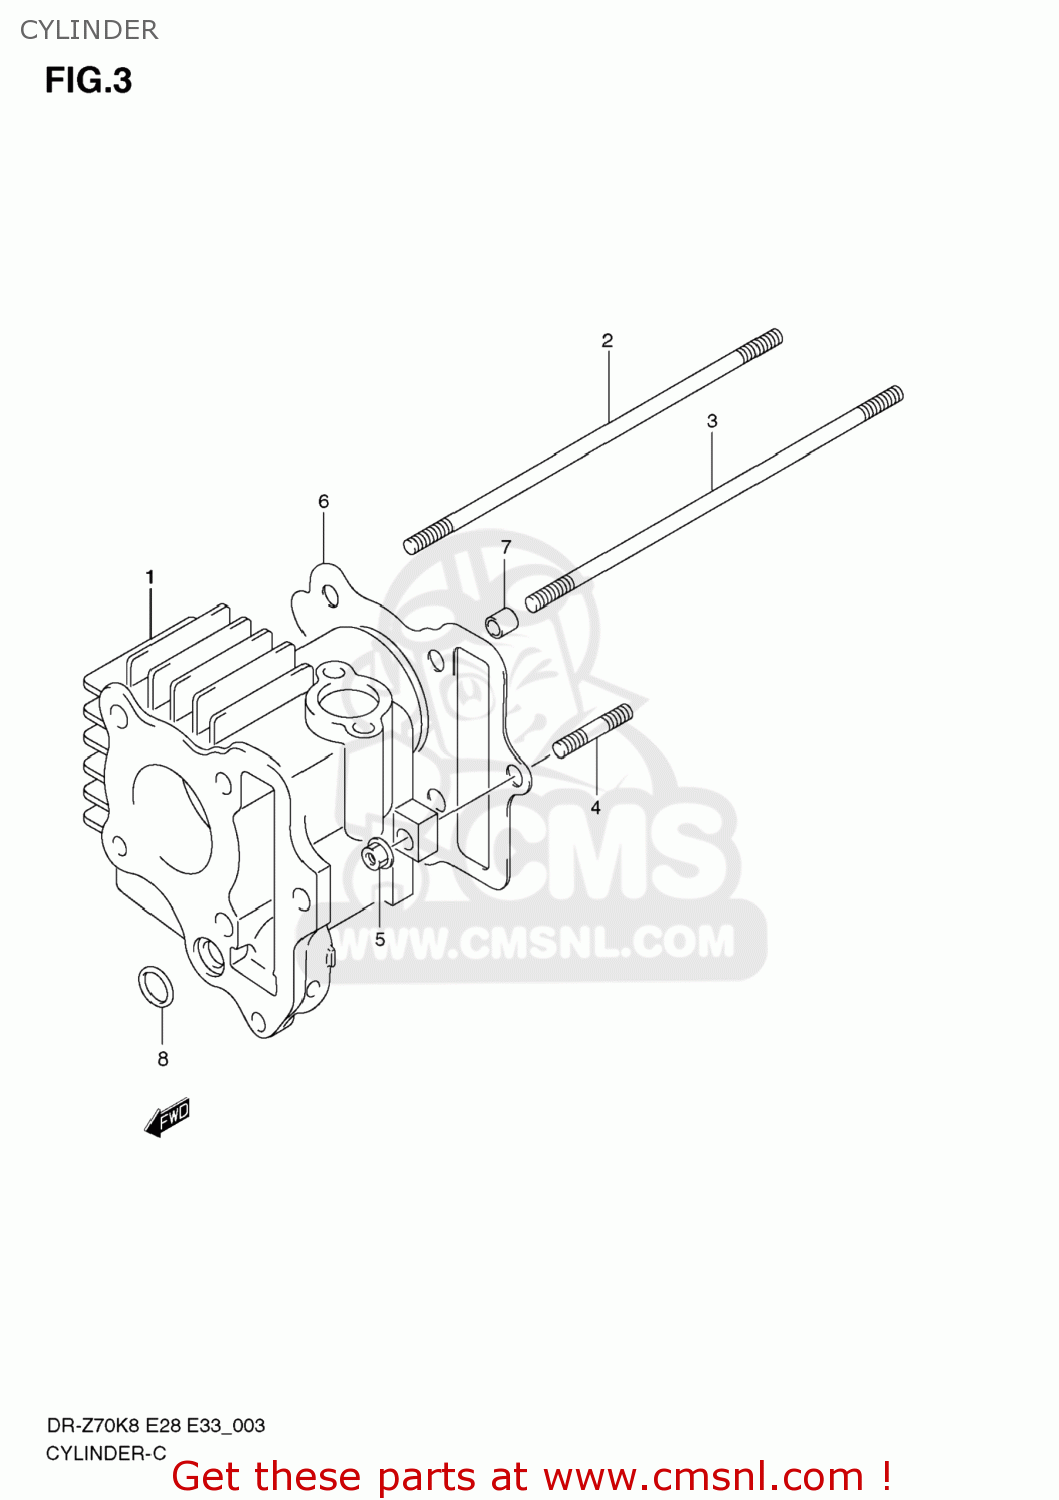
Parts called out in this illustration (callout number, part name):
1	CYLINDER
2	BOLT,STUD
3	BOLT,STUD
4	BOLT,STUD
5	NUT
6	GASKET,CYLINDER (NAS)
7	PIN(6.2X8X11)
8	O RING(D:2.4,ID:11.8)
